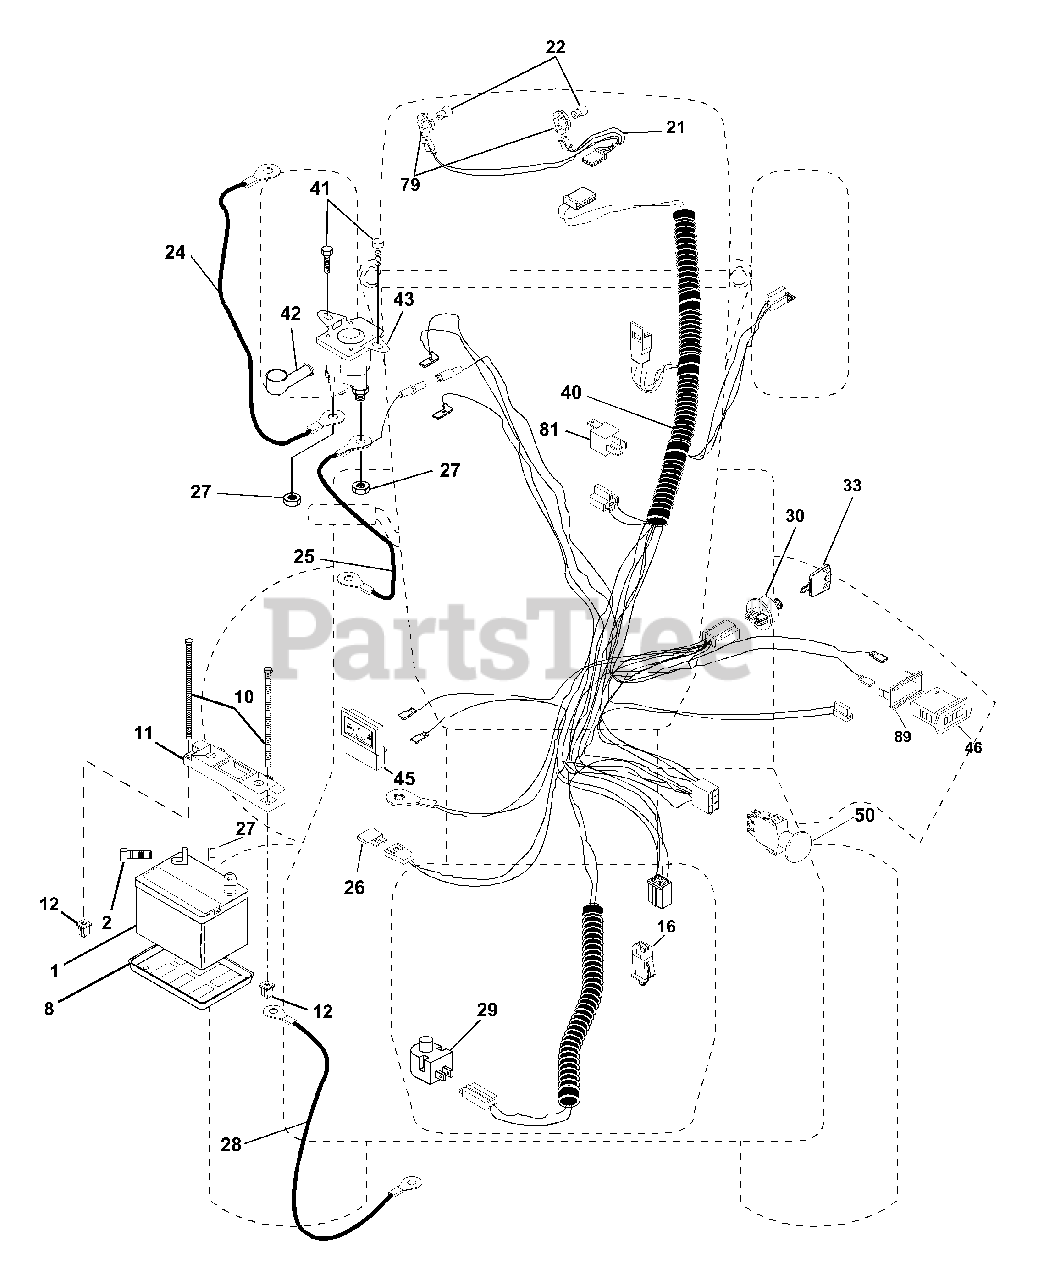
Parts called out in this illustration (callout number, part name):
1	Battery
2	Bolt Hex Head 1/4-20 x 3/4
8	Tray, Battery
10	Bolt, Battery Front 1/4-20 x 7.5 Zinc
11	Holddown Battery Front Mount
12	Nut, Push Nylon 1.4" Battery Front
16	Switch Interlock Push-In
21	Harness Socket Light w/4152J
22	Bulb Light
24	Cable, Battery
25	Cable, Battery
27	Nut Keps Hex 1/4-20
28	Cable,Ground
29	Switch, Plunger Normal Op Olive
30	Switch, Ign
40	Harness Ign.
41	Screw 1/4-20 x 1/2
42	Cover, Terminal Red
43	Solenoid
46	Hourmeter Snap-In
50	Switch, PTO
79	Bulbholder Asm
81	Relay Asm.
89	Bracket Snap-In Hourmeter
